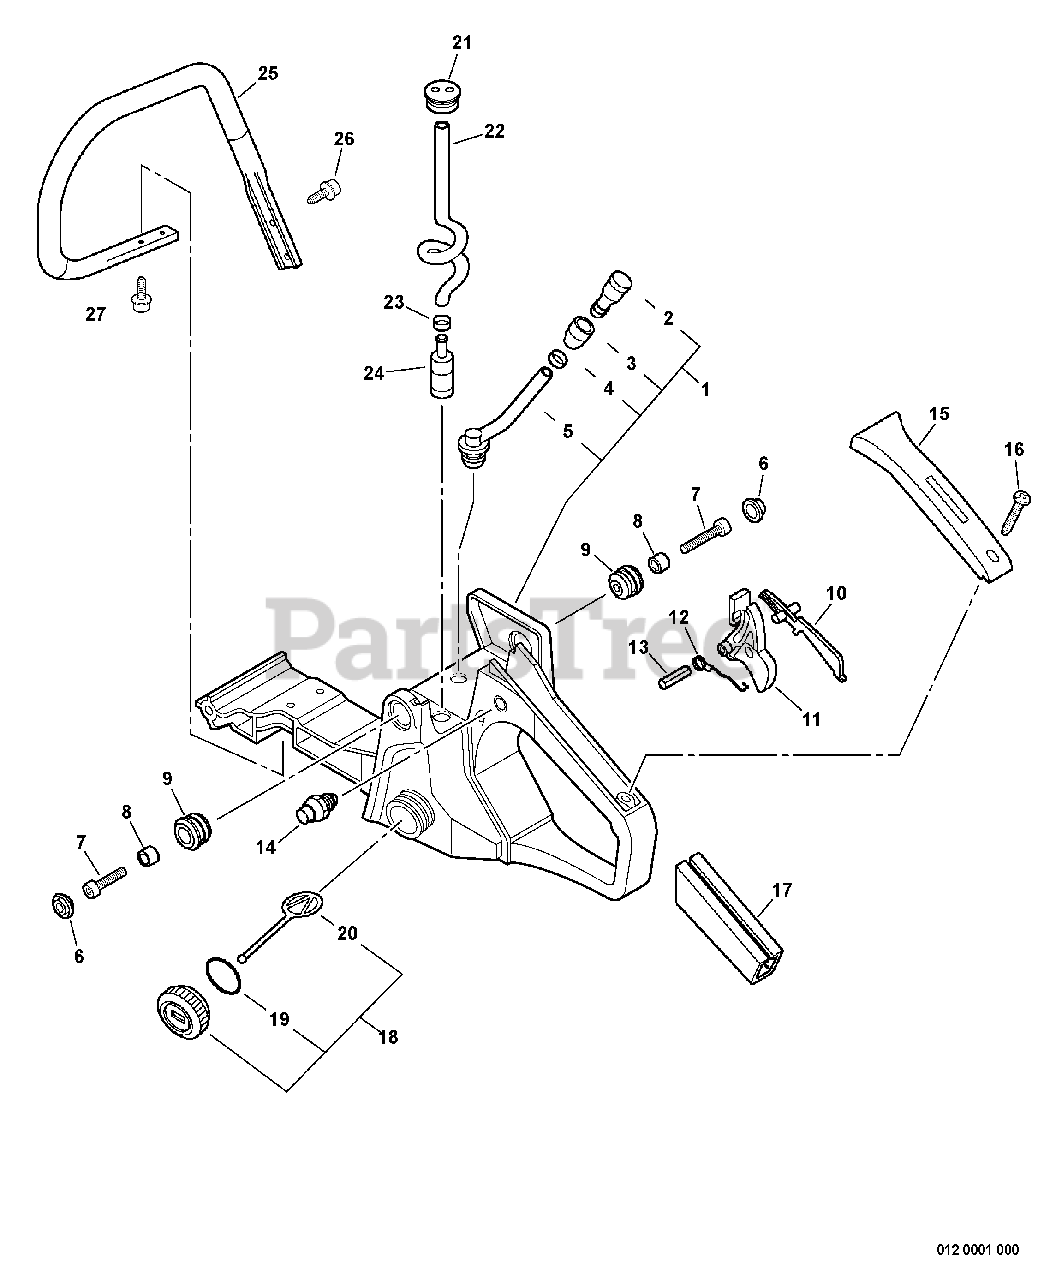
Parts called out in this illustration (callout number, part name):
1	REAR HANDLE SET
2	VENT ASSY
3	HOLDER, VENT
4	CLIP Ø6.5 MM
5	PIPE, VENT 3×6×65
6	CAP, CUSHION
7	BOLT, HEX 4×20
8	COLLAR 4
9	CUSHION 4
10	LOCKOUT, THROTTLE
11	TRIGGER, THROTTLE
12	SPRING, TORSION
13	PIN, SPRING 4×30
14	LOCK, THROTTLE TRIGGER
15	COVER, HANDLE
16	SCREW 4×14
17	GRIP, HANDLE
18	CAP ASSY
19	O-RING 22
20	CONNECTOR, CAP L= 60 MM
21	GROMMET, FUEL
22	PIPE, FUEL W/GROMMET 3×5×250L
23	CLIP 6 MM
24	FILTER, FUEL
25	HANDLE, FRONT - ALUMINUM
26	SCREW TAPPING 5×20
27	SCREW TAPPING 5×16
